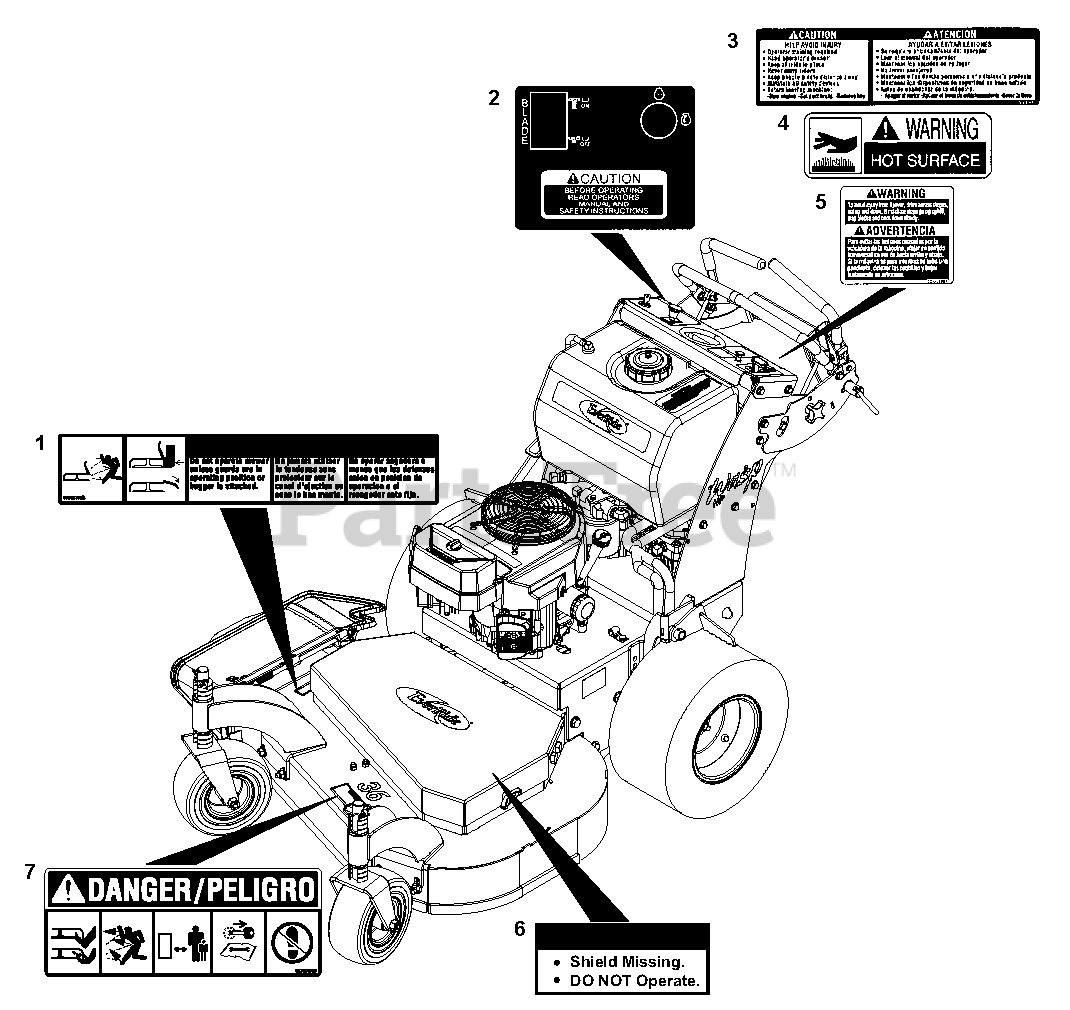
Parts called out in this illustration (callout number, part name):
1	Decal, Warning
2	Decal, PTO and Key Switch
3	Decal, General Caution
4	Label, Warning (Hot Surfaces)
5	Decal, Warning-Slope
6	Decal, Warning-Shield
7	Decal, Mower Pan Danger
